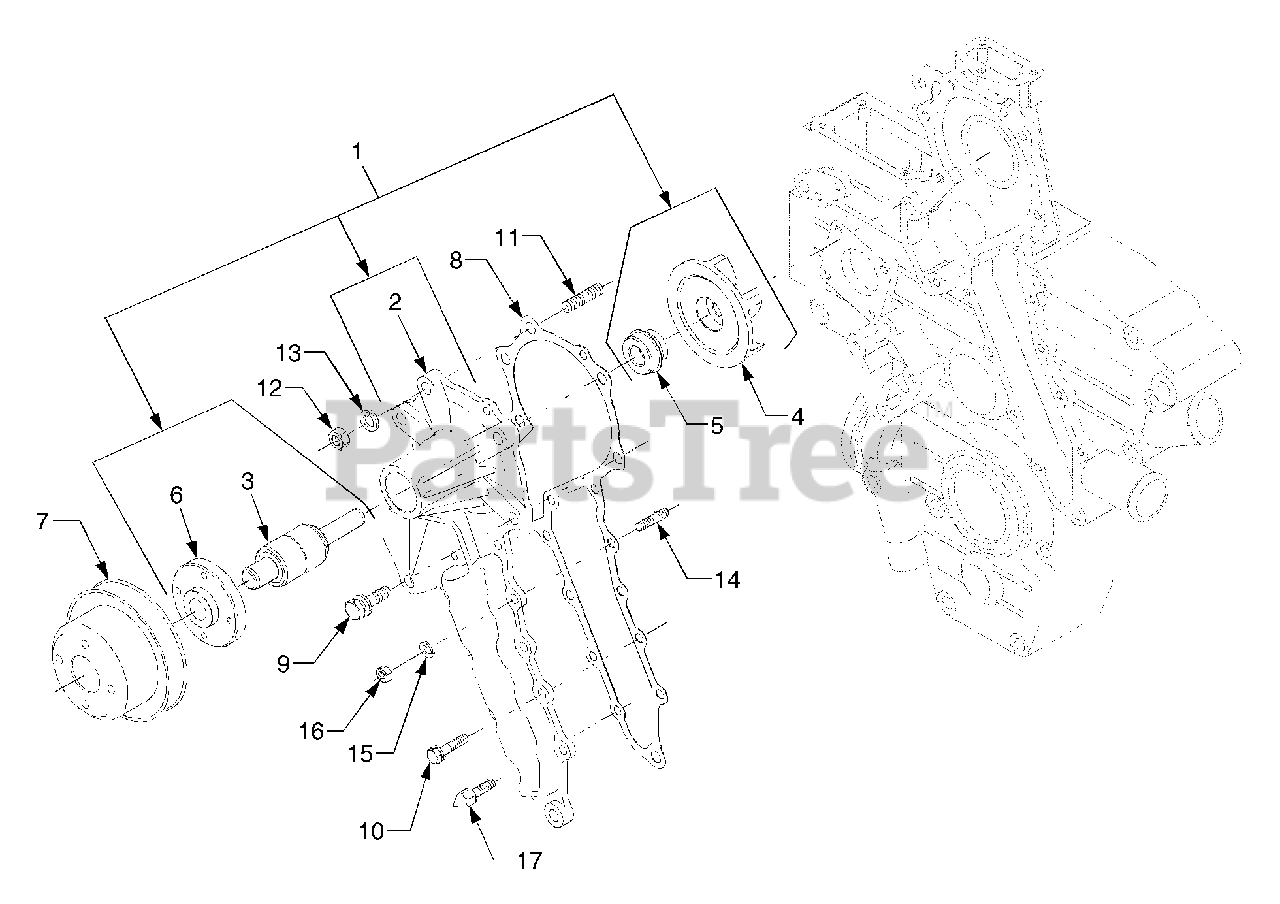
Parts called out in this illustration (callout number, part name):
1	Water Pump Ass'y
2	Body, Water Pump
3	Bearing, Water Pump
4	Impeller, Water Pump
13	Washer, Spring
15	Washer, Spring
